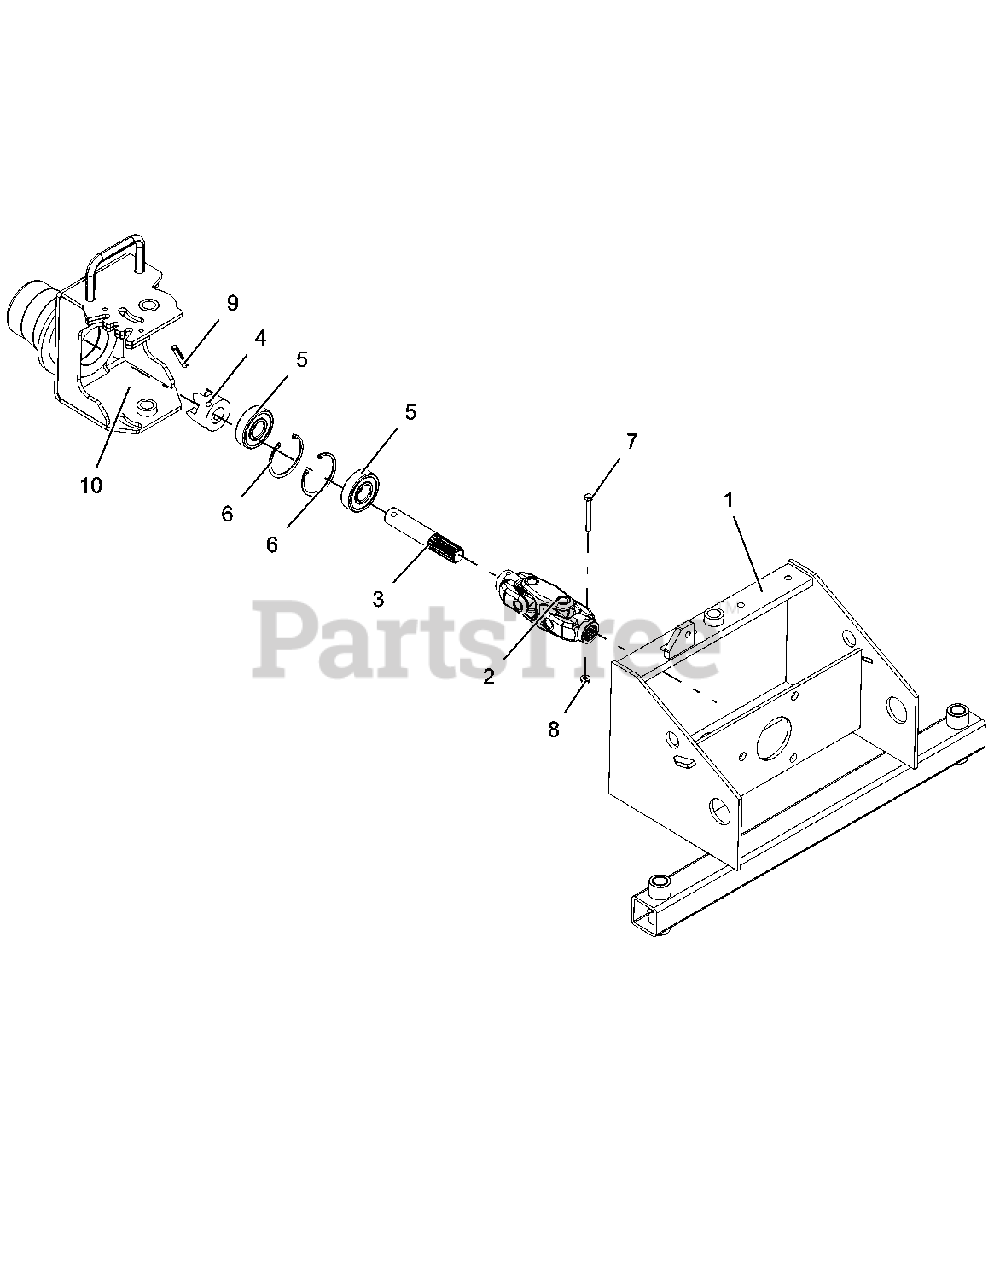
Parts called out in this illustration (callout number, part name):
1	WLDMT, BRUSH FRAME
2	ASM, JOINT DOUBLE
3	PTO SHAFT
4	CLAW COUPLING
5	BEARING, 6305LLC
6	RG-RTNG-INT 2.438X.078
7	BLT,HEX .25-20X2.25 G8ZC120
8	NUT,LK-NYL-FLG .25-20 G5ZC120
9	PIN-ROLL 8MM X 50MM
10	PIVOT HOUSING WLDMT
